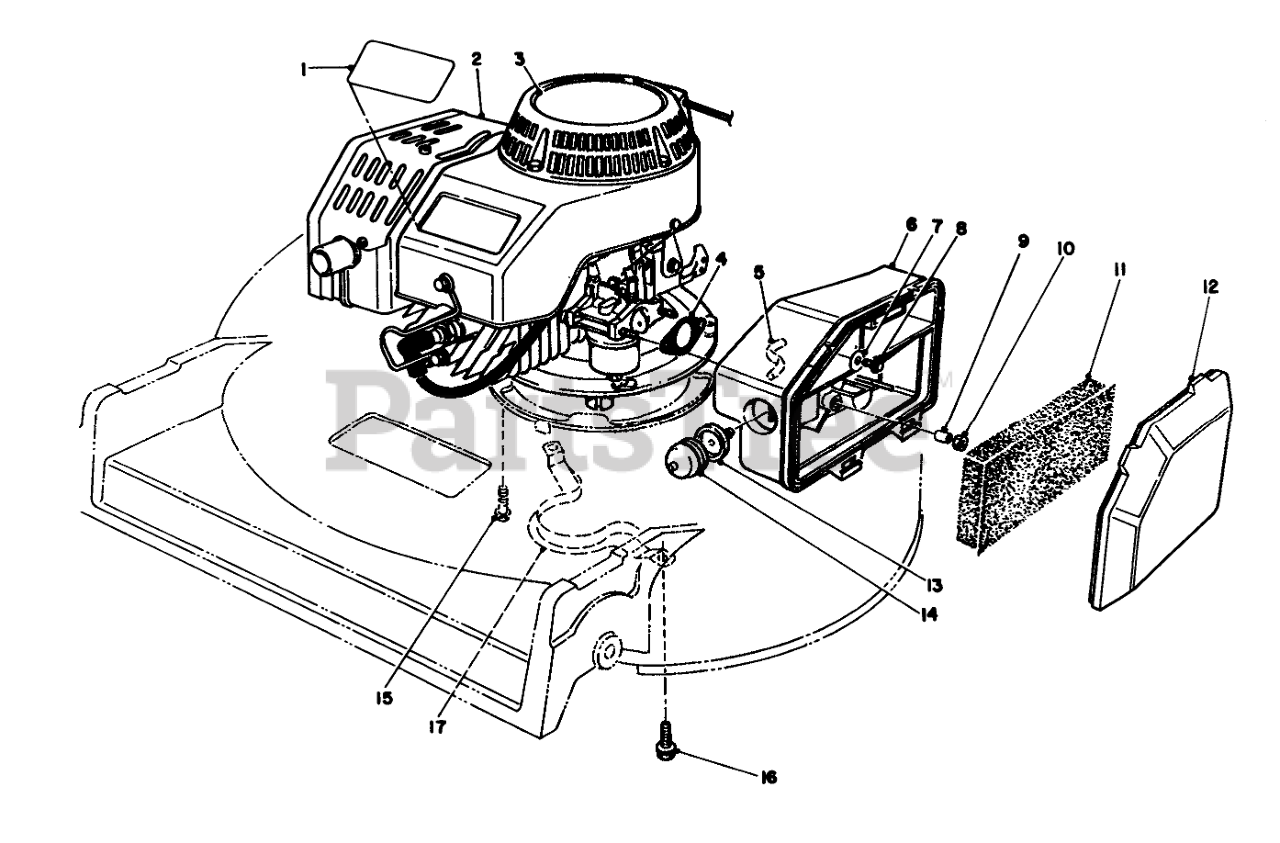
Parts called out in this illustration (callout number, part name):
1	DECAL - PROLINE
2	ENGINE ASM - BBC 2 CYCLE
3	DECAL-2 CYC RECOIL COMM
4	GASKET-AIR CLEANER
5	HOSE-PRIMER
6	BODY-AIR CLEANER
7	WASHER-FLAT
8	SCREW-HH
9	SPACER
11	ELEMENT-AIR CLEANER
12	COVER-AIR CLEANER
13	BODY-PRIMER
14	BULB-PRIMER
15	SCREW-HHF
16	SCREW-HWHTF
17	Guide-Belt
